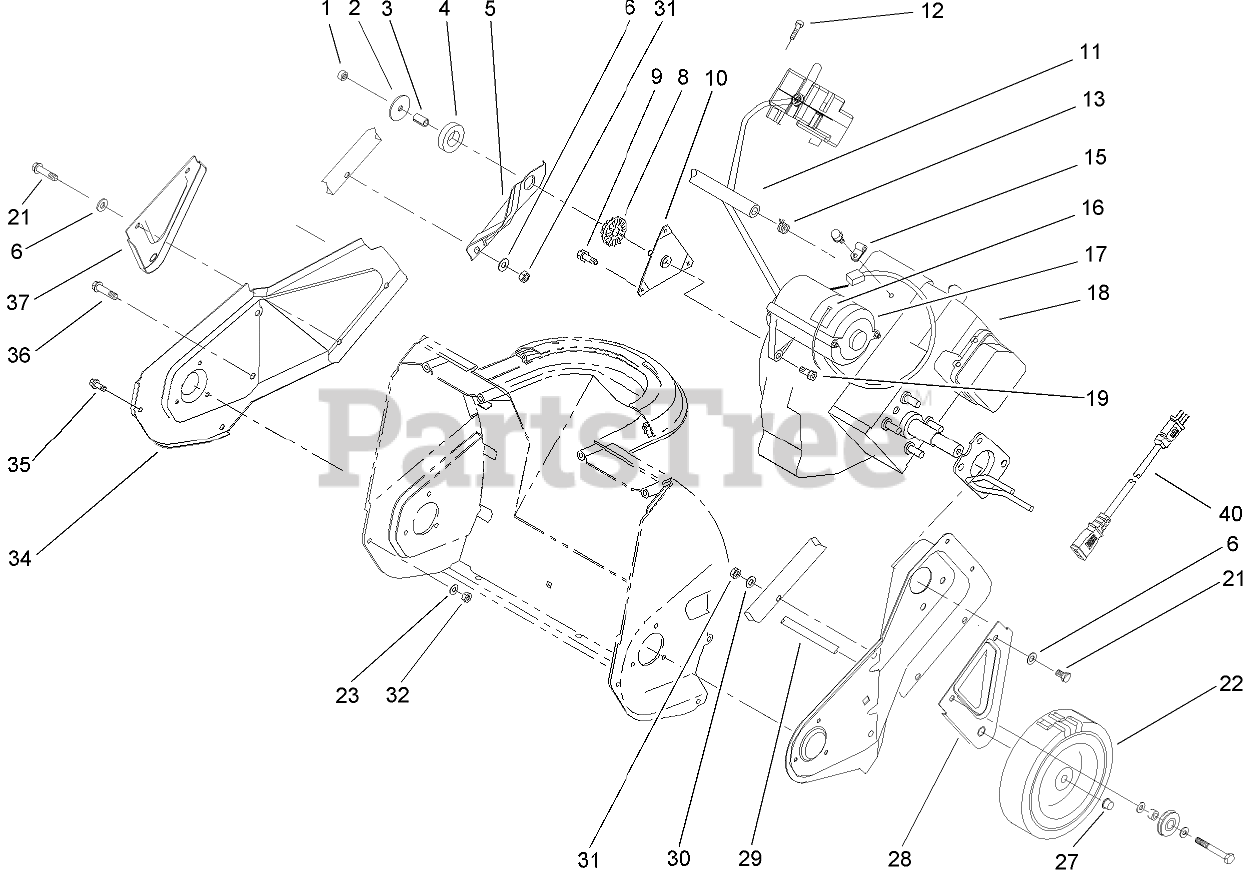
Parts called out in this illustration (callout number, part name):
1	NUT-LOCK, NI
2	WASHER-FLAT
3	SPACER-TUBULAR
4	RING-ISOLATOR
5	BRACKET-SUPPORT, ENGINE
6	WASHER-FLAT
8	BUSHING-ISOLATOR
9	SCREW
10	BRACKET AND STUD ASM
11	LINE-GAS
12	SCREW-PLASTITE
13	CLAMP-HOSE
15	CLAMP
16	TIE-CABLE
17	120 VOLT STARTER ASM
19	SCREW-HH, TORX
21	SCREW-HH
22	WHEEL
23	WASHER-FLAT
27	RETAINER-PUSH ON
28	BRACKET-WHEEL, LH
30	WASHER
31	NUT-LOCK, NI
32	NUT-LOCK, NI
34	PLATE-SIDE, RH
36	SCREW-PLASTIC
37	BRACKET-WHEEL, RH
40	CORD-ELECTRIC
